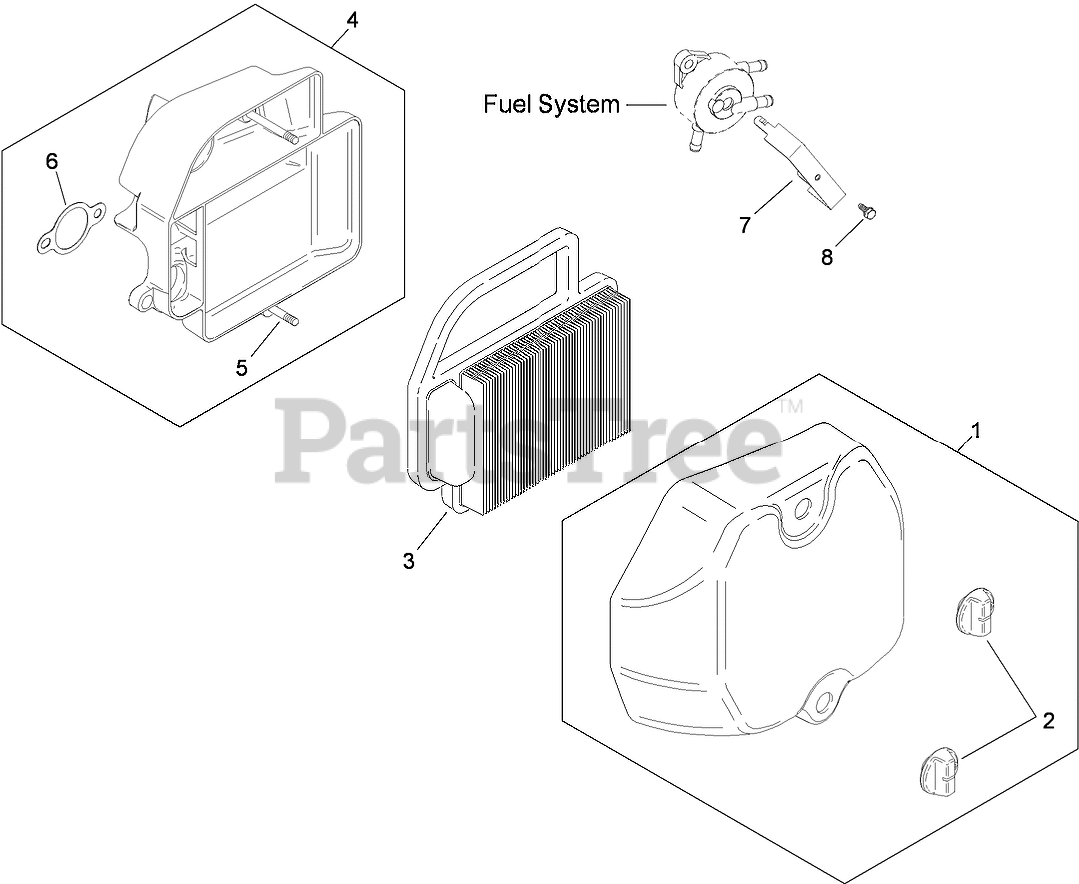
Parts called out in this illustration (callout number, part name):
1	AIR CLEANER COVER KIT (INCLUDES REF 2)
2	KNOB-COVER
3	Element-Cleaner, Air
4	AIR CLEANER BASE KIT (INCLUDES REF 5, 6)
5	STUD-BASE, AIR CLEANER
6	Gasket-Base, Air Cleaner
7	BRACKET-PUMP, FUEL
8	SCREW-THRD FRM (M4X0.7X10)
